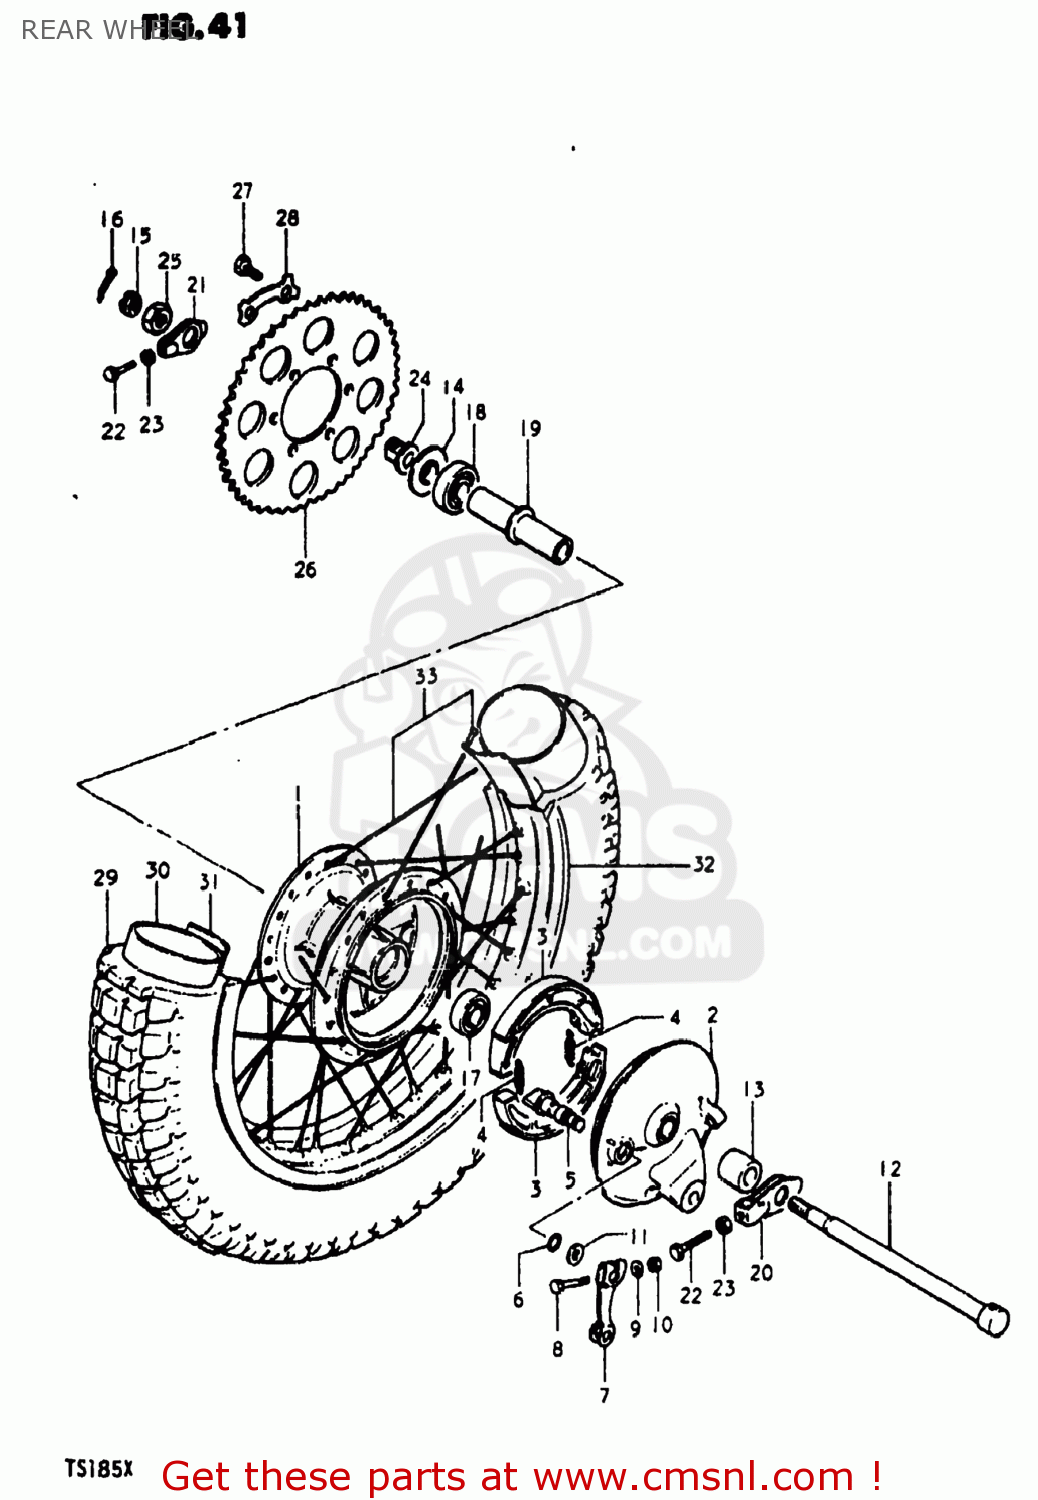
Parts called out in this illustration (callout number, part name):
1	HUB,REAR WHEEL
2	PANEL,RR BRAKE ANCHOR
3	SHOE,BRAKE
4	SPRING(L:34)
5	CAM,FRONT BRAKE
6	O-RING (D:2.4 ID:13.8)
7	LEVER,REAR BRAKE CAM
8	BOLT 6X40
9	WASHER
10	NUT
11	WASHER (14.5X22X1.6)
12	AXLE,REAR
13	SPACER(15.2X22X26)
14	SPACER,RR AXLE,L
15	NUT 12MM
16	COTTER PIN
17	BEARING
18	BEARING
19	SPACER,RR WHEEL HUB BEARING
20	ADJUSTER,CHAIN,R
21	ADJUSTER,CHAIN,L
22	BOLT(8X40)
23	NUT
24	SPACER,CHAIN ADJUSTER,L
25	NUT
26	SPROCKET,RR
27	BOLT(8X30)
28	WASHER
29	TIRE 4.10-18 105-458MM
30	TUBE ASSEMBLY,WHEEL,INNER
31	PROTECTOR,INNER TUBE
32	RIM,WHEEL(1.85X18)
33	SPOKE SET
